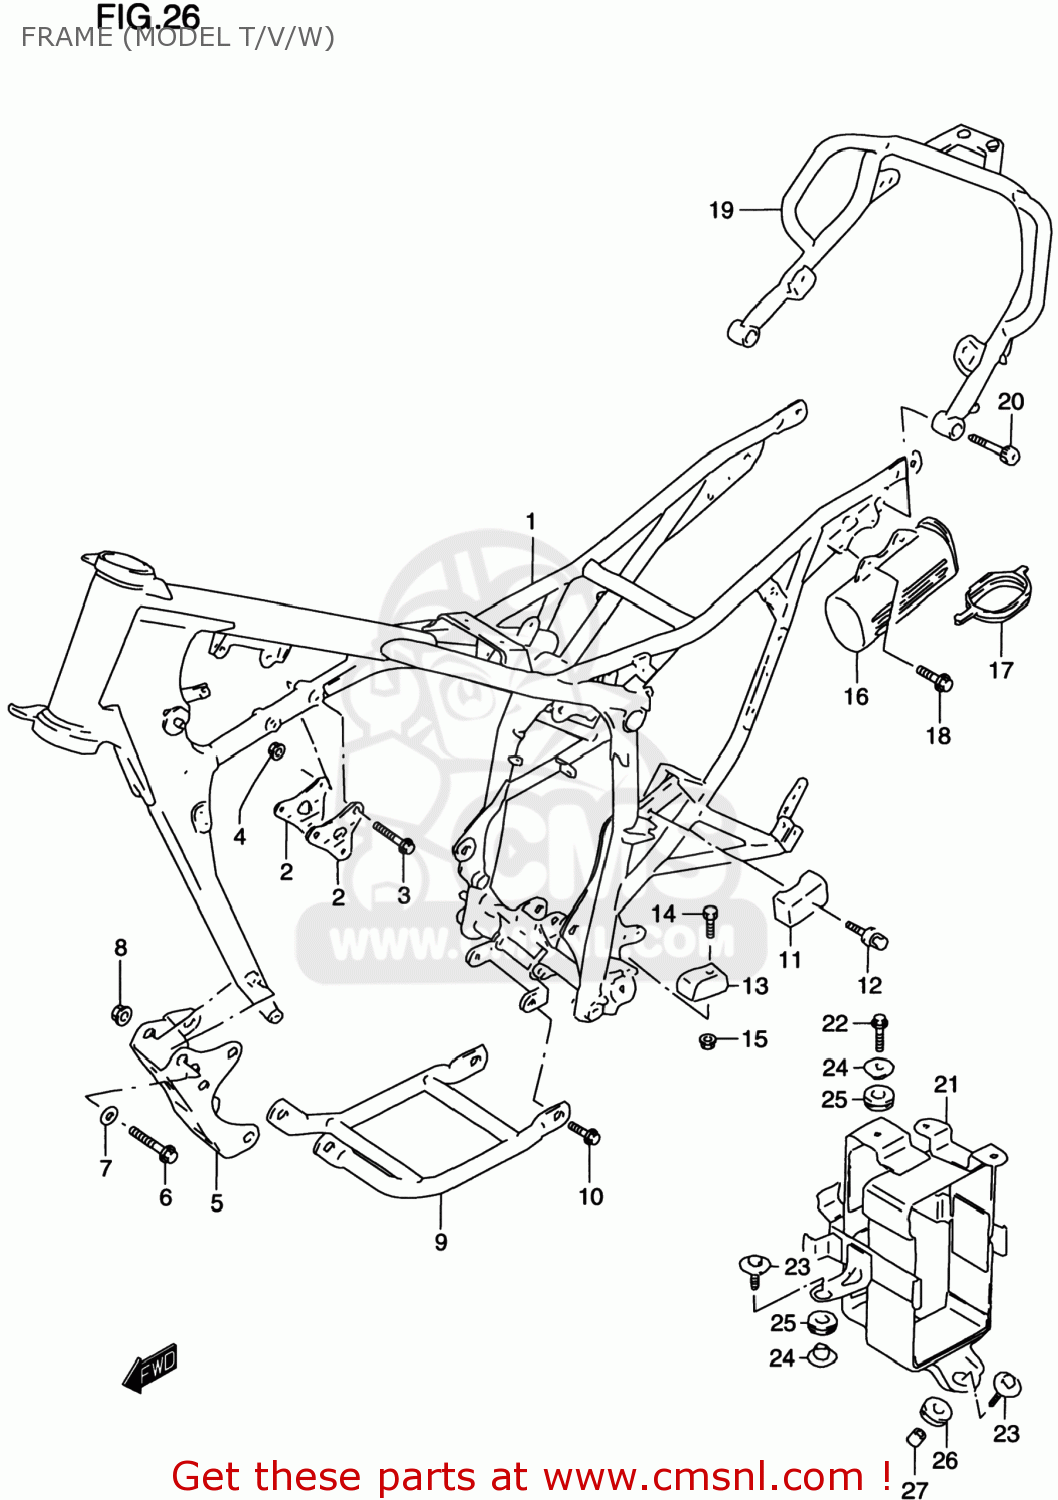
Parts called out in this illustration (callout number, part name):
1	FRAME COMP
2	PLATE,ENGINE MOUNT UPR
3	BOLT(8X53)
4	NUT
5	PLATE,ENG MTG LWR
6	BOLT(8X65)
7	LOCK WASHER
8	NUT
9	PROTECTOR COMP,ENGINE
10	BOLT
11	GUIDE,CH CONTROL UPR
12	BOLT
13	GUIDE,CHAIN CONTROL LWR
14	BOLT
15	NUT
16	HOLDER,TOOL
17	CAP,HOLDER
18	BOLT 6X16
19	GRIP,RR
20	BOLT(8X30)
21	HOLDER,BATTERY
22	BOLT
23	BOLT(6X25)
24	WASHER
25	CUSHION
26	CUSHION
27	SPACER(6.5X10X9)
